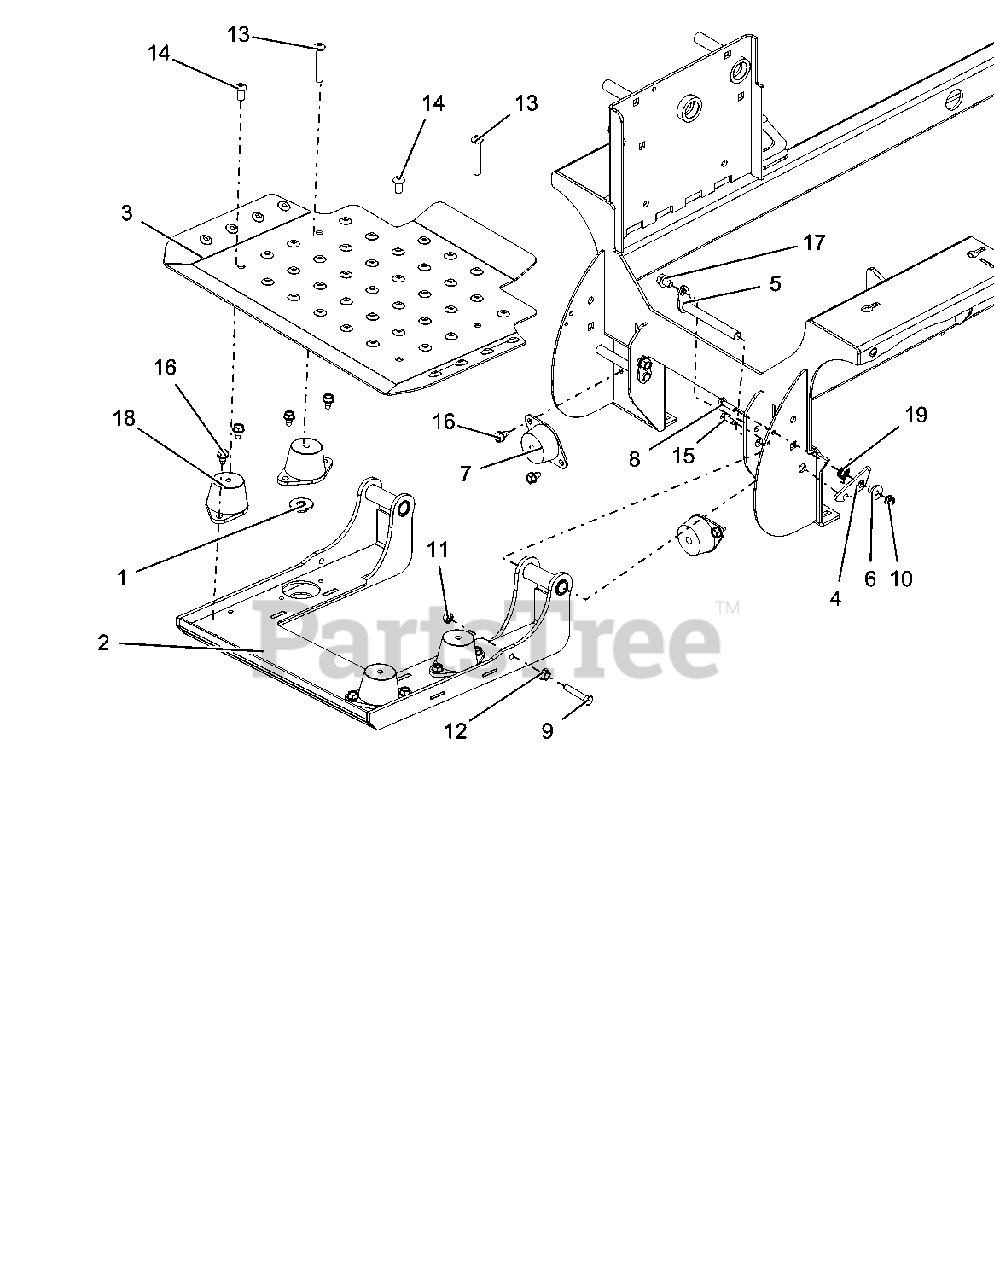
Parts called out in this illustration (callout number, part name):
1	WLDMT, SEAT RETAINER
2	WLDMT, OPERATOR PLATFORM
3	PLATE, OPERATOR PLATFORM
4	LATCH, PLATFORM
5	WLDMT, PIN
6	BUSH, FLG .26 .X .42 X .88
7	MOUNT, ENGINE, VIBRATION ISO
8	@BLT-HEX .25-20X1.00 GR5 YWZC
9	@BLT-HEX .31-18X1.75 GR5 YWZC
10	@NUT-LK-NYL-FLG .25-20 YWZC
11	@NUT-LK-CTR .31-18 YWZC
12	@NUT-SPNLK-FLG .312-18 YWZC
13	BLT-BTHD-SOCKET .38-16X2.25FTH
14	BLT-BTHD-SOCKET .38-16X.75
15	SCR-TAP-PM .25-20X.75 TR YWZ
16	@SCR-TAP .31-18X.50 HWH TR YWZ
17	@SCR-TAP .38-16X.50 HWH TR YWZ
18	MOUNT, ISOLATOR
